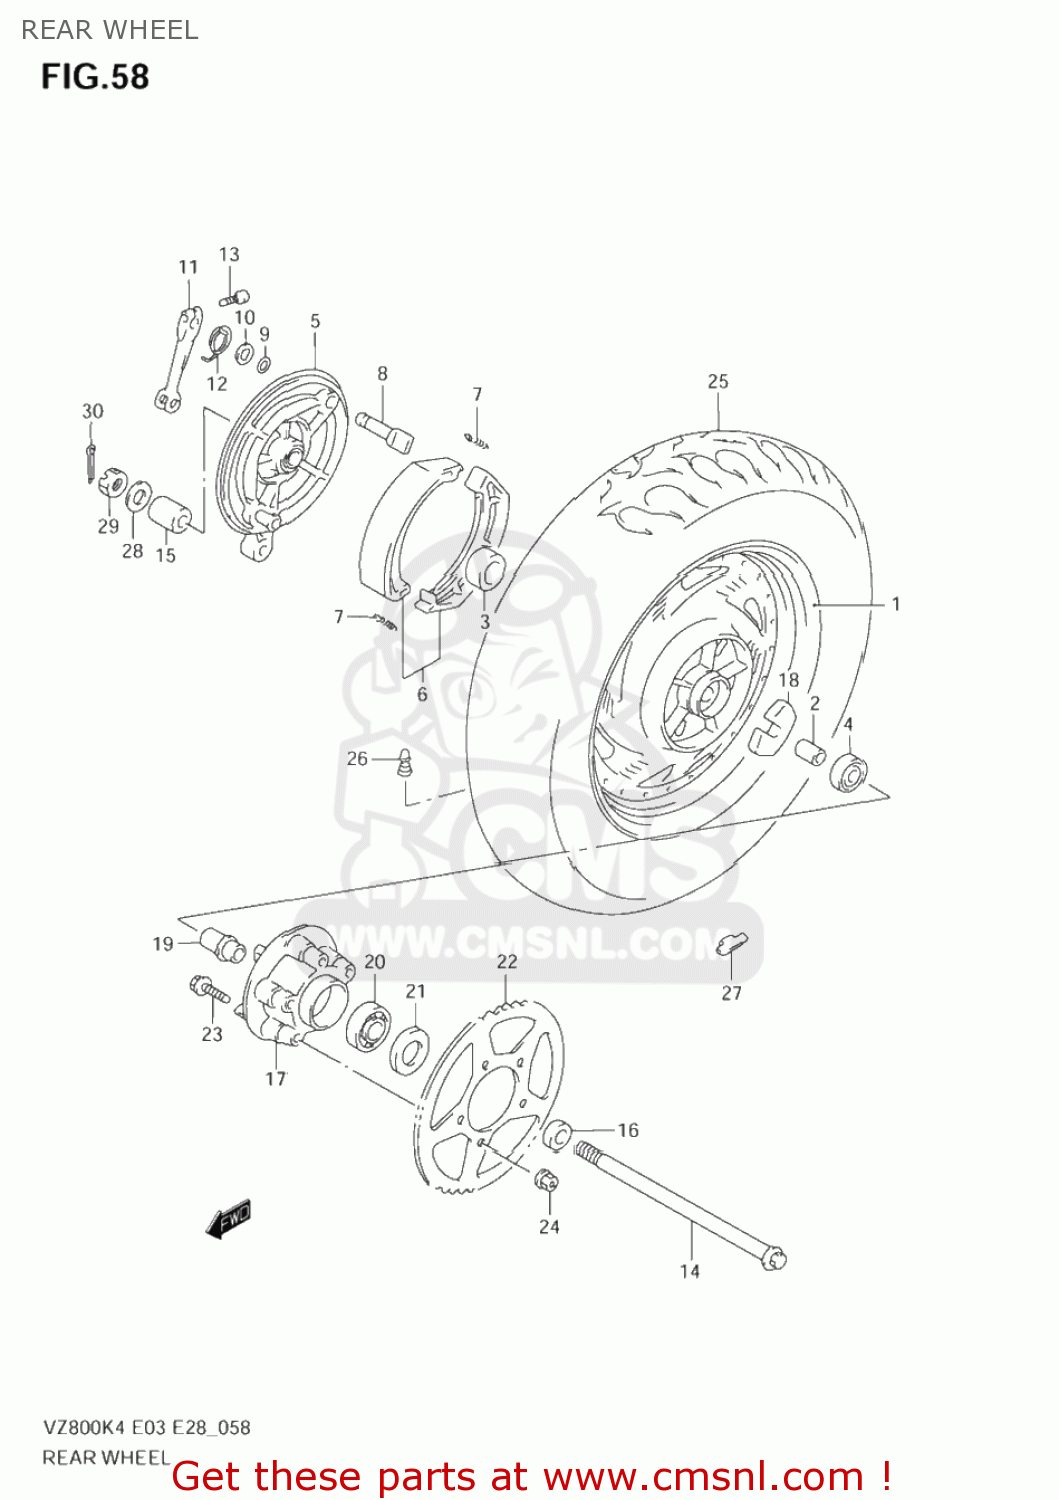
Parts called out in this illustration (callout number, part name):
1	WHEEL,RR(15M/CXMT3.50)
2	SPACER(17.5X25X70)
3	BEARING
4	BEARING
5	PANEL,RR BRAKE ANCHOR
6	SHOE SET,BRAKE (NAS)
7	SPRING,BRAKE SHOE
8	CAM,RR BRAKE
9	O RING(D:2.4,ID:14.8)
10	WASHER(15.5X24X1.6)
11	LEVER,RR BRAKE CAM
12	SPRING
13	BOLT
14	AXLE,RR
15	SPACER(17X33X35.3)
16	SPACER,RR AXLE,L
17	DRUM,RR SPROCKET MOUNTING
18	ABSORBER,RR HUB SHOCK
19	RETAINER,RR SPROCKET DRUM
20	BEARING(25X62X17)
21	SEAL,OIL(35X62X8)
22	SPROCKET,RR(NT:48-530)
23	BOLT
24	NUT
25	TIRE,RR(150/90 15M/C 74H)
26	VALVE ASSY,WHEEL RIM(TR412)
27	WEIGHT,WHEEL BALANCE 10G
28	WASHER(16.2X30X2.6)
29	NUT
30	PIN, COTTER
